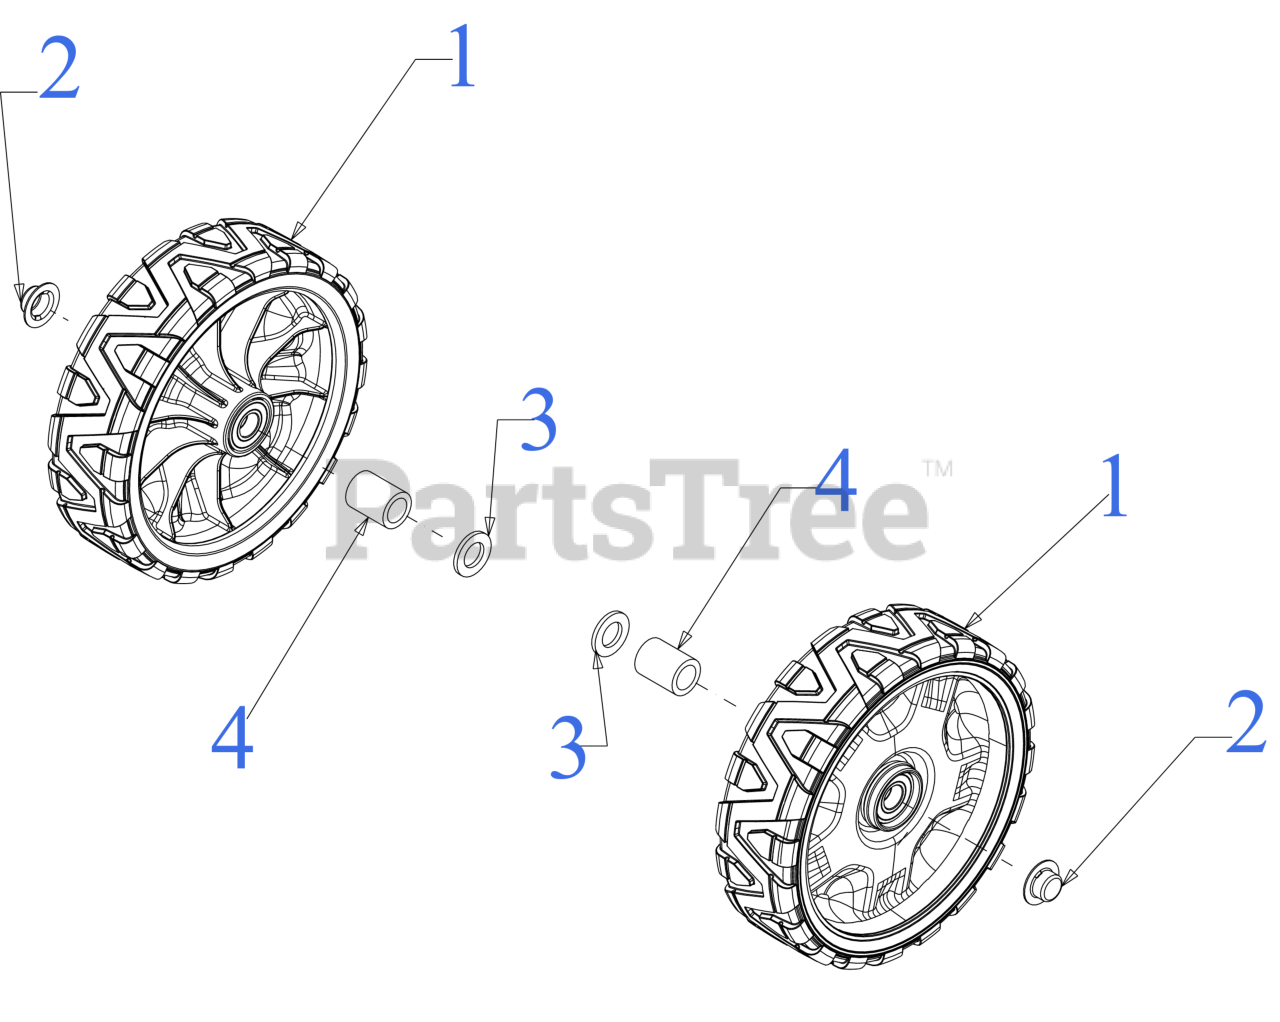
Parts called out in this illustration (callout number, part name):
1	WHEEL ASSEMBLY (7 x 2)
3	FLAT WASHER .535 x .930 x .090
4	SPACER .525 x .775 x 1.015
